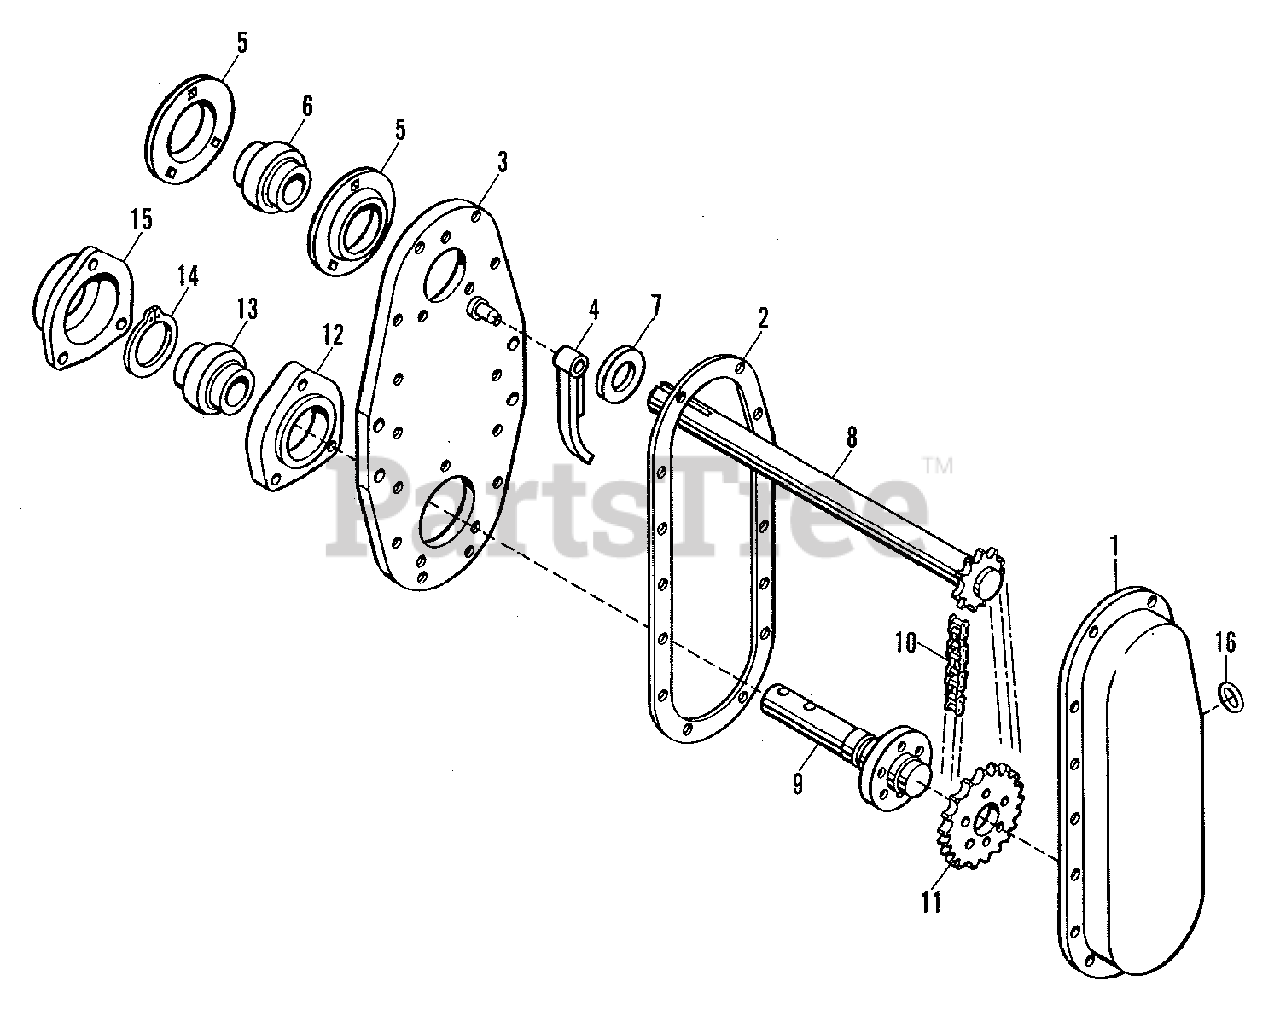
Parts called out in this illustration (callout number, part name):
1	COVER, Chaincase
1	CAPSCREW, 5/16NC x 1/2
1	CAPSCREW, 5/16NC 1
1	LOCKWASHER, 5/16
1	CAPSCREW, Full Thread, 1/2NC x 2
1	WASHER, Plain, 1/2 x 1 x 14 Ga.
1	NUT, Jam, 1/2NC
2	GASKET, Cover
3	PLATE, Chaincase
4	TIGHTENER, Chain
5	FLANGE, Bearing
5	CAPSCREW, 3/8NC x 3/4
5	LOCKWASHER, 3/8
8	SHAFT, Input
9	SHAFT, Output
10	CHAIN ASSEMBLY, Roller, #60 Heavy
11	CAPSCREW, 3/8NC x 1
11	LOCKWASHER, 3/8
12	HOUSING, Bearing
14	RING, Retaining
15	SHIELD, Dust
15	CAPSCREW, 3/8NC x 1-1/2
15	LOCKWASHER, 3/8
